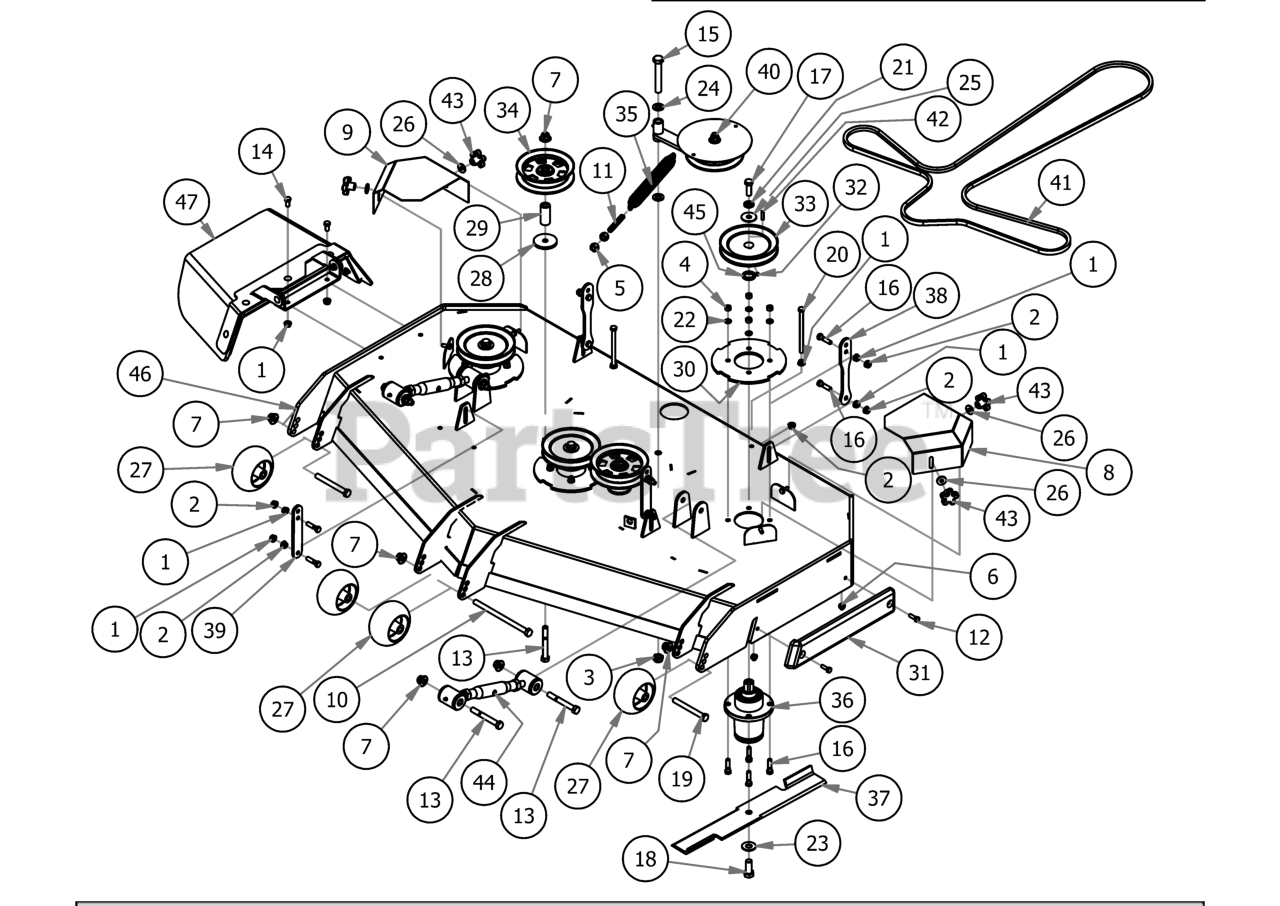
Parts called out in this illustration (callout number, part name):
1	3/8" Flange Nut
2	3/8" Nylock Flange Nut
3	5/8-11 Nylon Insert Jam Half Nut
4	3/8" Hex Nut
5	1/2" Hex Nut
6	5/16" Nylon Flange Nut
7	1/2-13 NYLON INSERT FLANGE LOCKNUT ZINC
8	2019 Stand On 54" Pulley Cover Trim
9	2019 Stand On 54" Pulley Cover Discharge
10	1/2-13 x 8 Hex Bolt Grade 5
11	All Thread-Pump Idler Tensioner
12	5/16" x 1" Bolt
13	1/2" x 4" Bolt (Grade 8)
14	3/8" x 3/4" Hex Bolt
15	5/8" x 4" Hex Bolt
16	3/8" x 1 1/2" Hex Bolt
17	1/2"-20 x 1 1/2 - Grade 5 Fine Thread Bolt
18	5/8 x 1 1/2 Grade 8 Hex Bolt (Fine)
19	1/2" x 4 1/2" Bolt
20	3/8-16 x 5 1/2 Hex Bolt
21	1/2" Lock Washer Zinc
22	3/8" Lock Washer
23	5/8'' Flat Washer
24	.630 ID Plastic Washer
25	1/2" Belleville Washer
26	.360 ID Plastic Washer-Black
27	2019 Deck Wheel
28	MZ Deck Idler Spacer
29	2019 Revolt Stationary Idle Spacer
30	Deck Spindle Support Plate
31	REVISED TRIM BUMPER_20180226
32	5/16 Set Screw
33	6 1/4" Drive Pulley
34	5-3/4 Idler Pulley
35	2019 Outlaw Gen2 Deck Spring
36	Spindle Assembly
37	61 inch Fusion Blade
38	2019 Stand-On Rear Deck Hanger
39	2019 Stand on deck hanger_front
40	2020 61 Revolt Deck Idler Assembly
42	1/4" x 1" Key
43	5/16" Knob
44	Turnbuckle
45	Spacer, 1x1.375x.25
46	Stand On 61 Deck Weldment
47	2019 Outlaw Gen2 Chute Assembly
